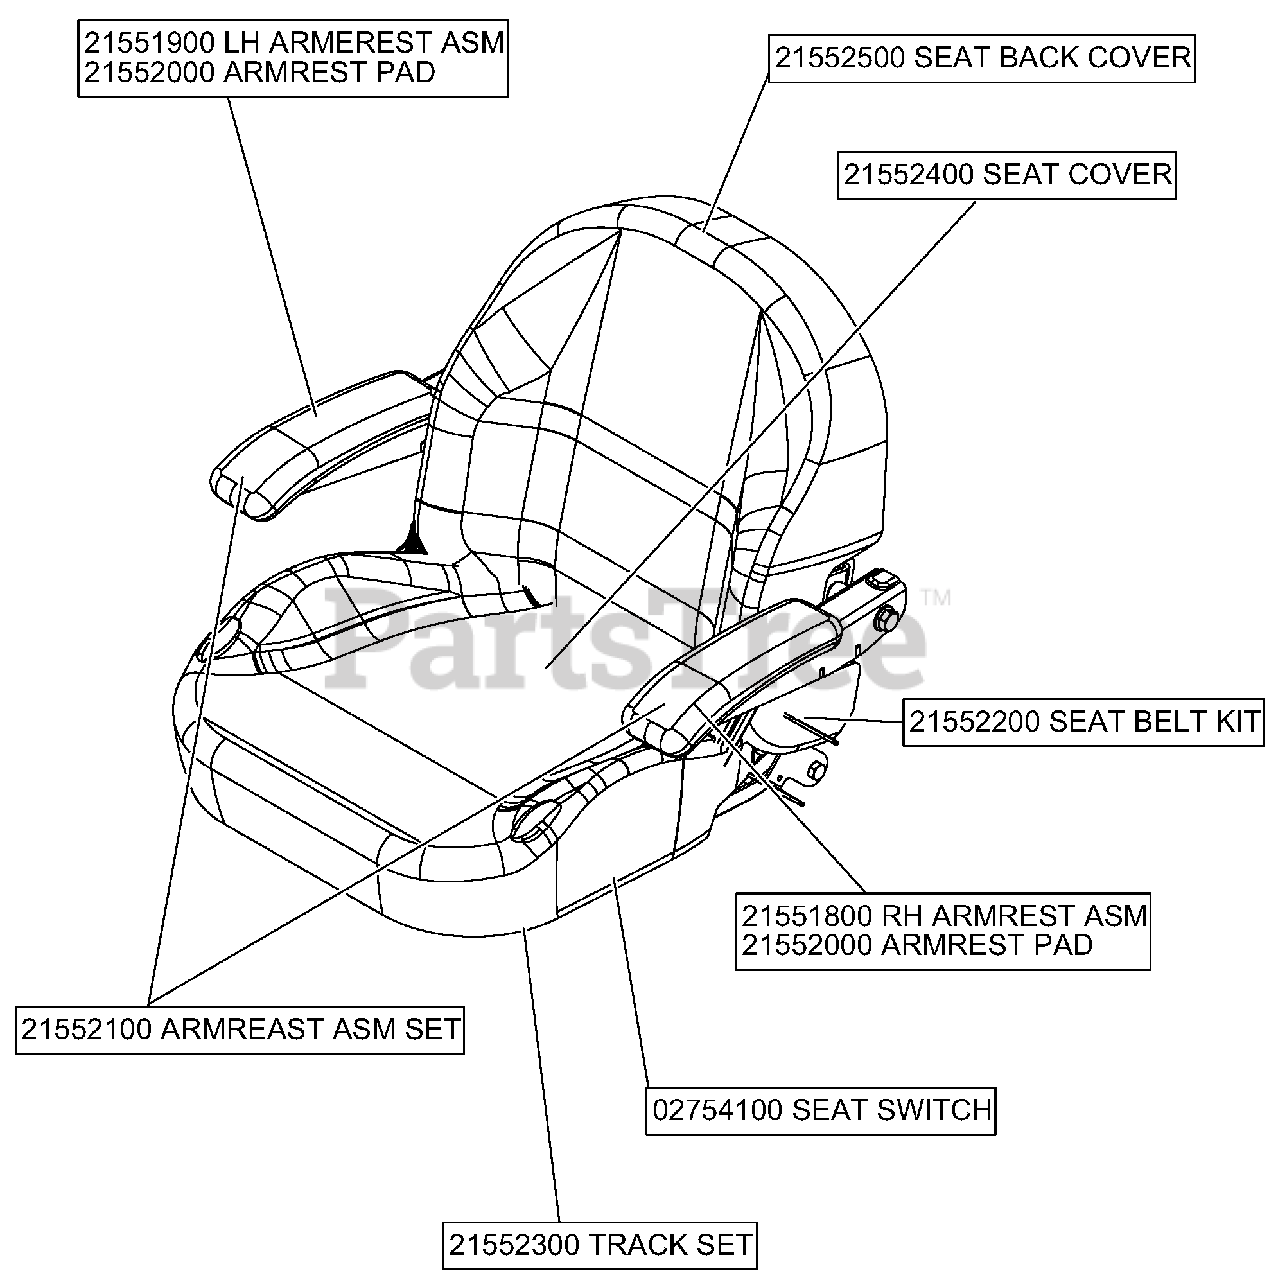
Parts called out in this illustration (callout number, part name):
1	LH ARMREST ASM
1	ARMREST PAD
2	SEAT BACK COVER
3	SEAT COVER
4	SEAT BELT KIT
5	RH ARMREST PAD
5	ARMREST PAD
6	SEAT SWITCH
7	TRACK SET
8	ARMREST ASM SET
